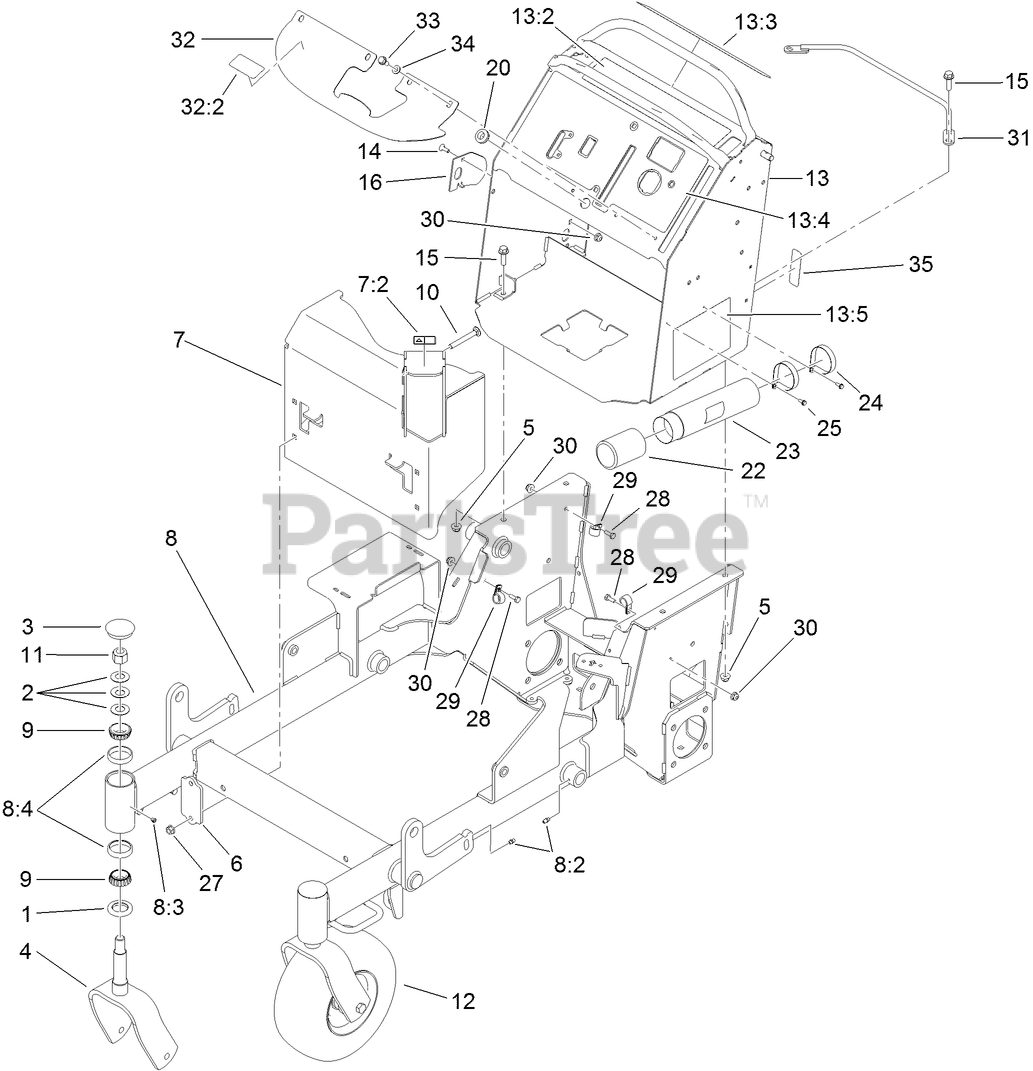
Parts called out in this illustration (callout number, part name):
1	SEAL-GREASE
2	WASHER-BELLVILLE
3	CAP-GREASE
4	FORK-CASTER
5	NUT-HF, NI
6	BRACKET-MOUNTING, GUARD
7	MUFFLER GUARD ASM
7:2	DECAL-WARNING
8	FRAME ASM
8:2	FITTING-GREASE
8:4	CUP-BEARING
9	BEARING-ROLLER, TAPERED
10	SCREW-CARR
11	NUT-LOCK, NI
12	WHEEL/TIRE AND BEARING ASM
13	CONTROL TOWER ASM
13:2	DECAL-OPC
13:3	DECAL-WARNING
13:4	DECAL-PANEL, CONTROL
13:5	DECAL-SERVICE/SPARK ARREST
14	BOLT-CARR
15	SCREW-HHF
16	PLATE-STRIKER
20	GROMMET
22	CAP-HOUSING
23	TUBE-MANUAL
24	CLAMP-R
25	SCREW-TAPTITE
27	NUT-HF
28	SCREW-HH
29	CLAMP-CABLE
30	NUT-HF
31	RETAINER-CABLE
32	COVER-TANK
32:2	DECAL-FILL, FUEL
33	SCREW-HWHTF
34	WASHER-FLAT
35	DECAL-FUSE
